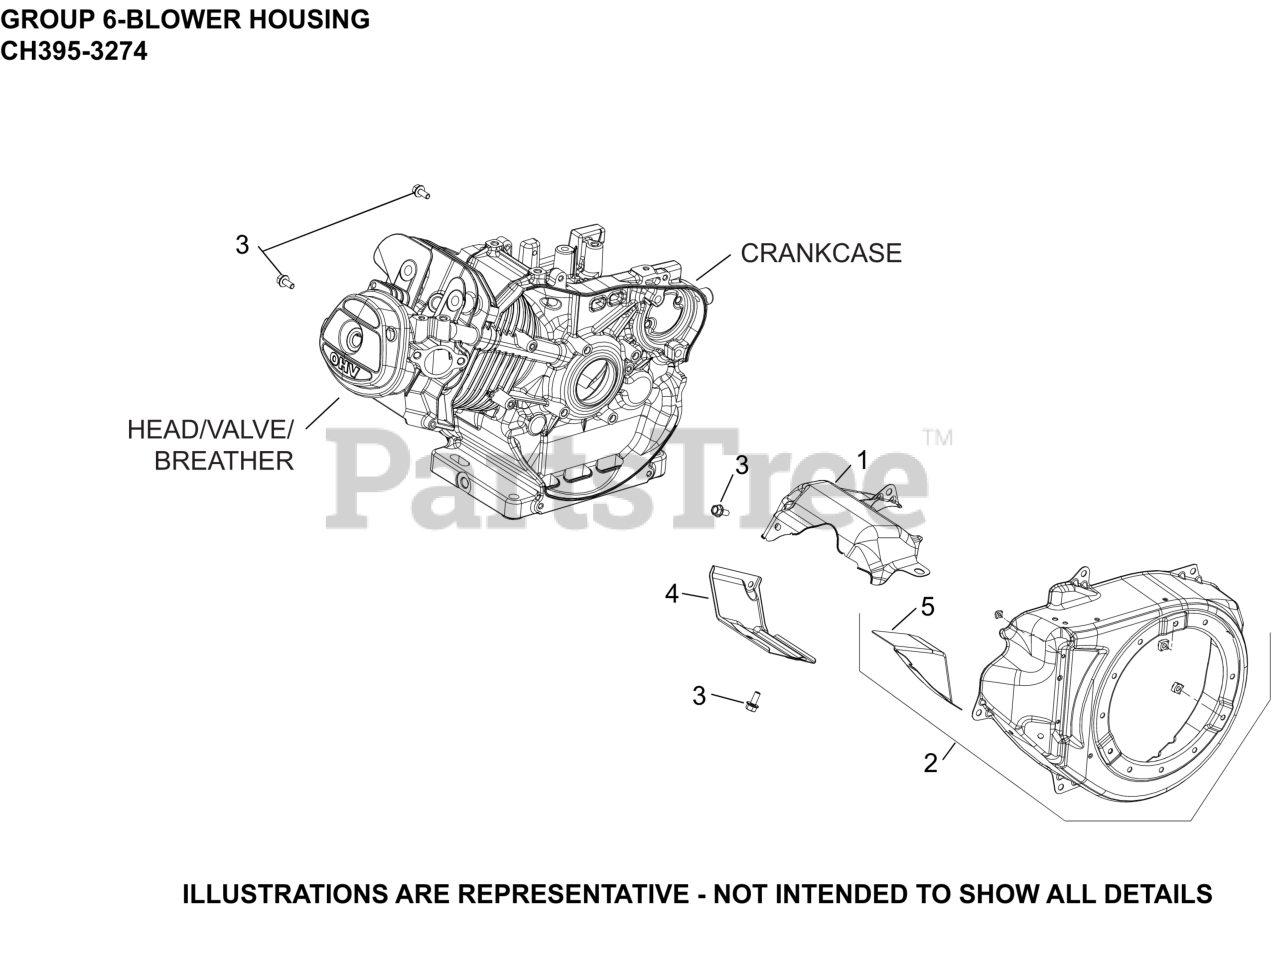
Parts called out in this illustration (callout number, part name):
1	SHIELD, UPPER HEAT
2	HOUSING, BLOWER ASSEMBLY
3	SCREW, HEX FLANGE (M6)-USE 25 086 433-S
4	SHIELD, CYLINDER HEAD
5	SHIELD, OUTSIDE CYLINDER HEAD
